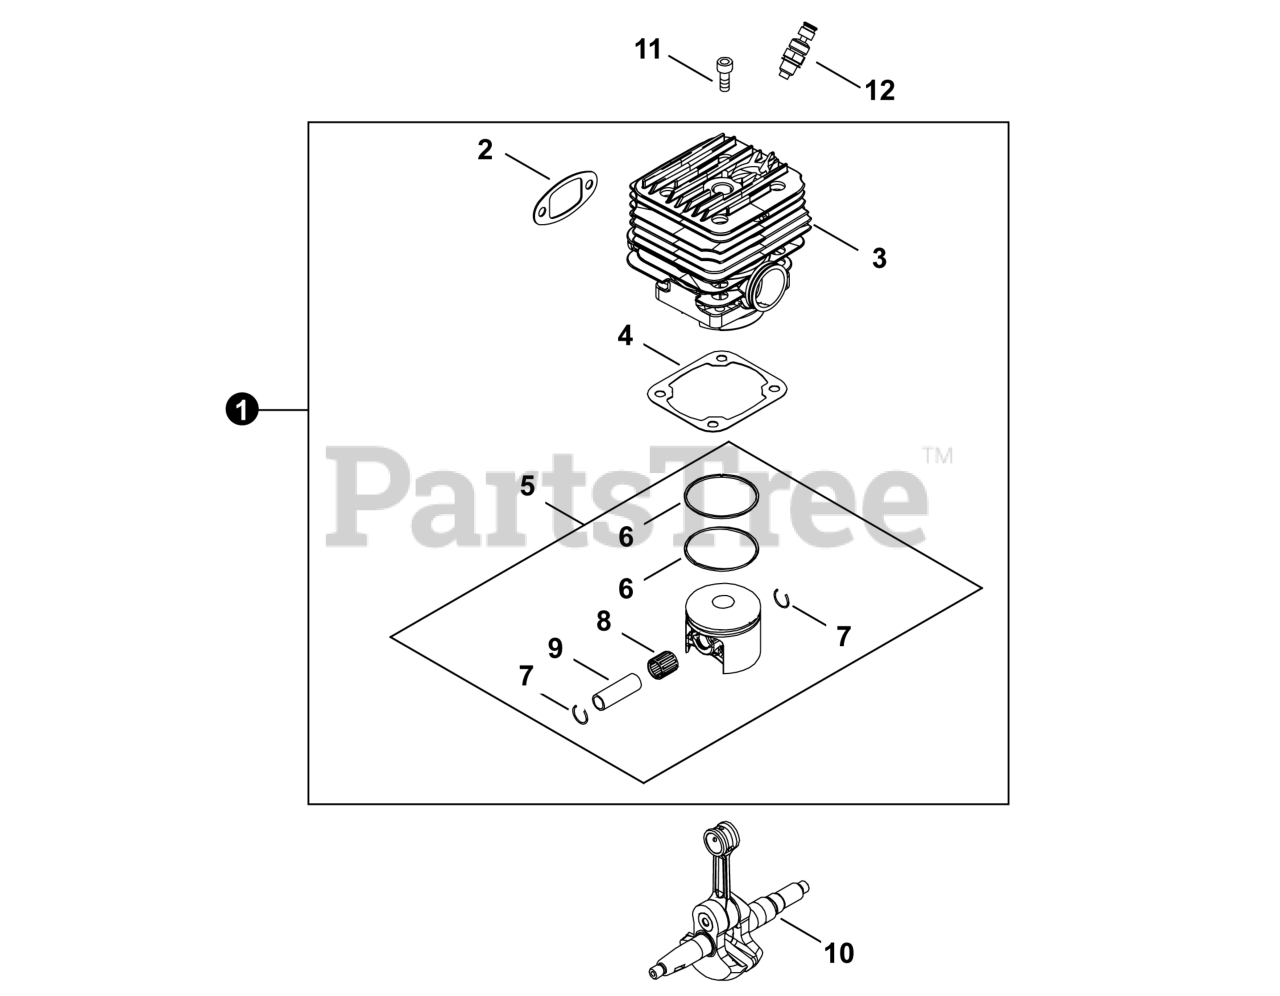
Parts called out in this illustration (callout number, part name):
1	CYLINDER/PISTON KIT
2	GASKET, EXHAUST
3	CYLINDER
4	GASKET, CYLINDER
5	PISTON KIT
6	RING, PISTON
7	RING, SNAP
8	BEARING, NEEDLE 12
9	PIN, PISTON 12
10	CRANKSHAFT ASSY
12	DECOMPRESSION ASSY
